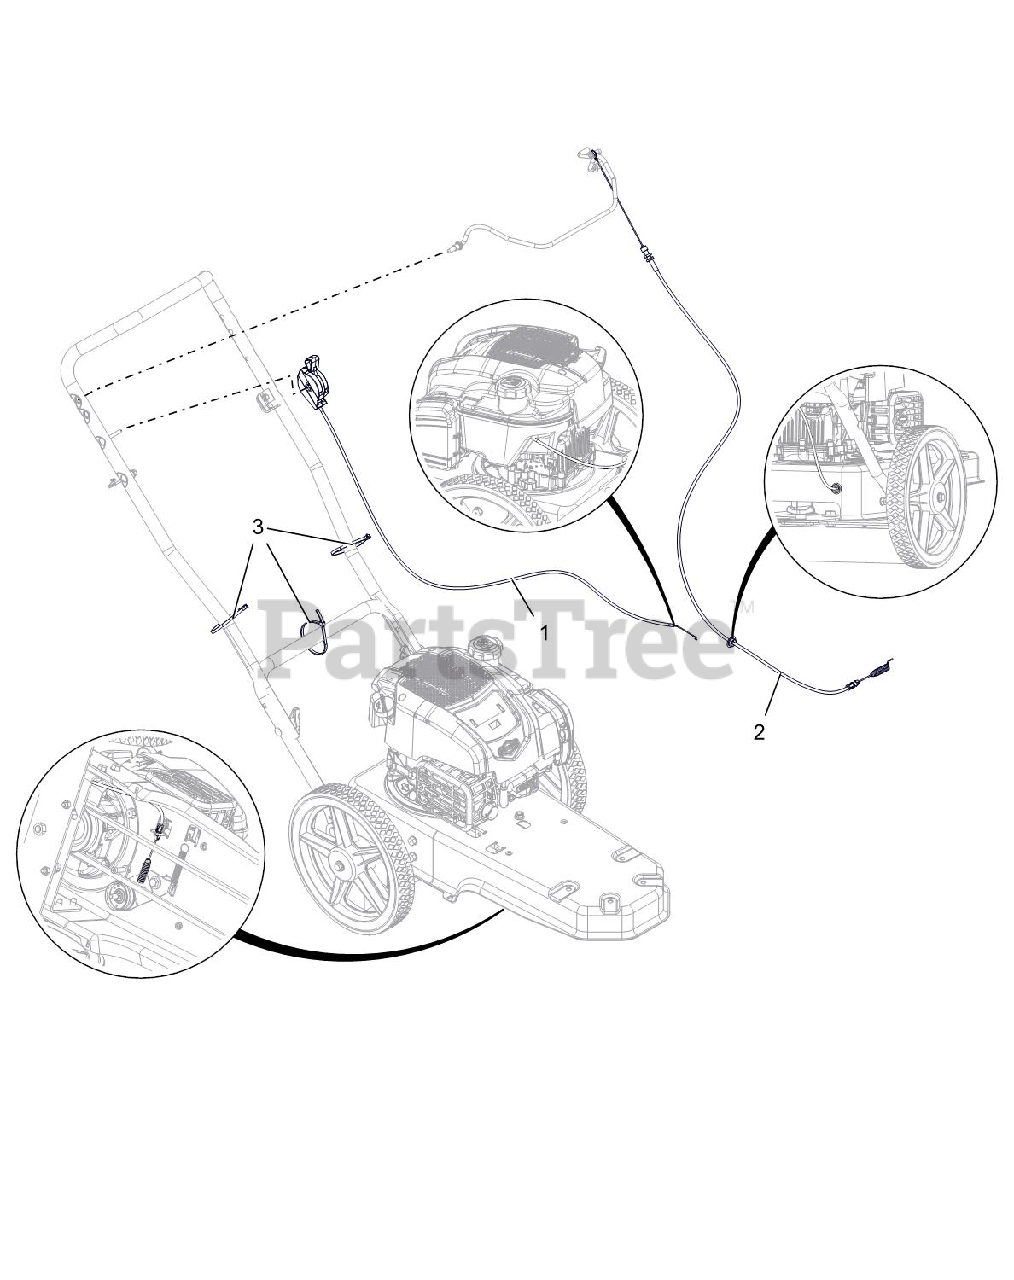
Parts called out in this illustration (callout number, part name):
1	CABLE, BRIGGS TRIMMER THROTTLE
2	CABLE - CONTROL
3	CABLE TIE LG 5-1/2
